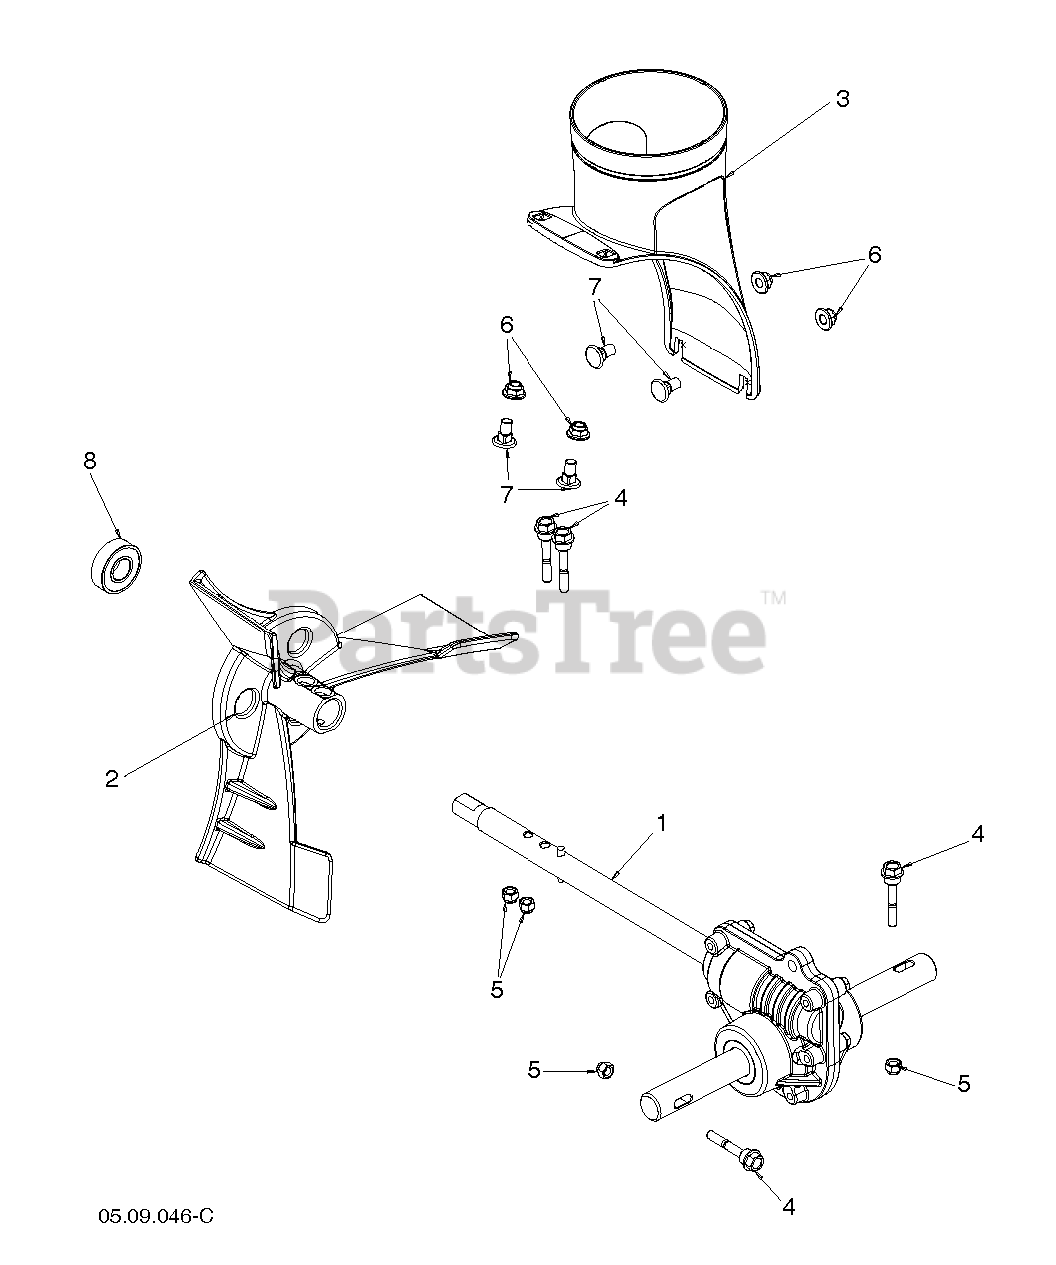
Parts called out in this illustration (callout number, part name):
1	GEARBOX CAST DD SHAFT
3	CHUTE BASE CAST ALUM HUSQ SIL
4	BOLT SHEAR HX HD 1/4-20 CLEAR
5	NUT HEXAGON 1/4-20 ST ZPB
6	NUT HEX FLG NYLOCK BLK 5_16-1
7	BOLT CARR WAFER BLK 5_16-18 X
